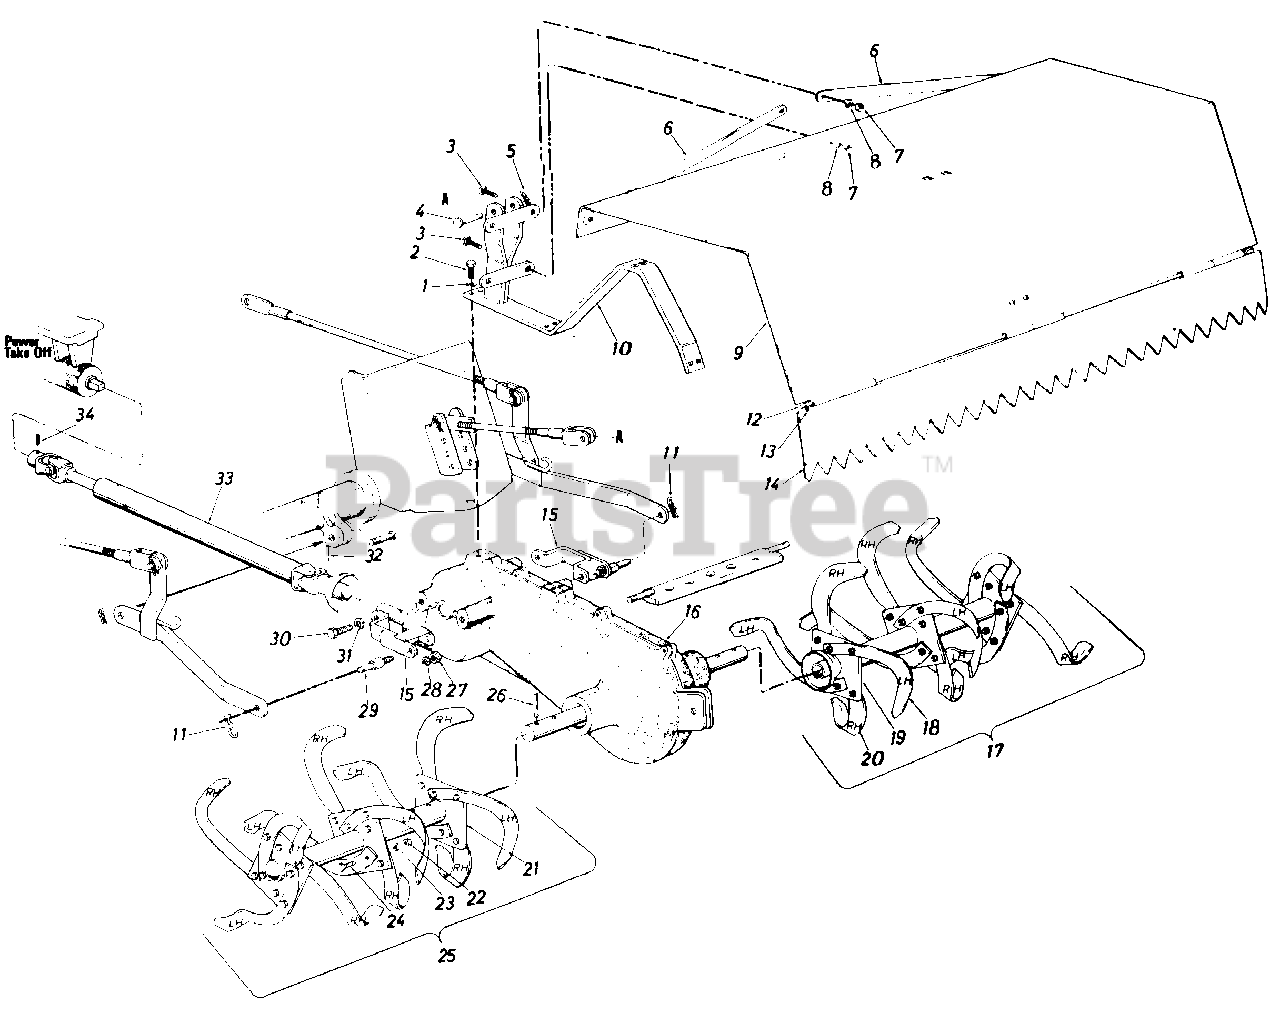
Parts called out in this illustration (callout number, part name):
1	L.-Wash. 1/2" Scr.*
2	Hex Scr. 1/2-13 x 1.25" Lg.*
3	Carriage Bolt 5/16-18 x 1.00" Lg.*
4	Clevis Pin 5/8" Dia. 2.4" Lg.
5	Internal Cotter Pin 5/8" Dia.
6	Tiller Cover Strap
7	Hex Nut 5/16-18 Thd.*
8	L. Wash. 5/16" Scr.*
9	Tiller Cover Ass'y.
10	Cover Brk't. Ass'y.
11	Internal Cotter Pin 5/8" Dia.
12	Cover Flap Rod
13	Cotter Pin 1/8" Dia. x 1.00" Lg.*
14	Cover Flap Ass'y.
15	Tiller Pivot Brk't. Ass'y.
16	Gear Box Ass'y. Comp.
17	Right Hand Tine Ass'y. Comp.
18	14" Tine L.H.
19	Mounting Adapter R.H.
20	14" Tine R.H.
21	Mounting Adapter L.H.
22	Hex Nut 3/8-24 Thd.*
23	L.-Wash. 3/8" Scr.*
24	Hex Scr. 3/8-24 x 1.25" Lg.*
25	Left Hand Tine Ass'y. Com
26	Spring Pin Spirol 3/8" Dia. x 2.00" Lg.
27	Hex Cent. L.-Nut 5/8-18 Thd.
28	L.-Wash. 5/8" Scr.*
29	Link Clevis Pin
30	Hex Scr. 5/8-11 x 1.50" Lg.*
31	L.-Wash. 5/8" Scr.*
32	Spring Pin Spirol 5/16" Dia. x 1.75" Lg.
33	Universal Drive Shaft Ass'y.
34	Sq. Hd. Set Scr. 3/8-16 x .50" Lg. Cup
